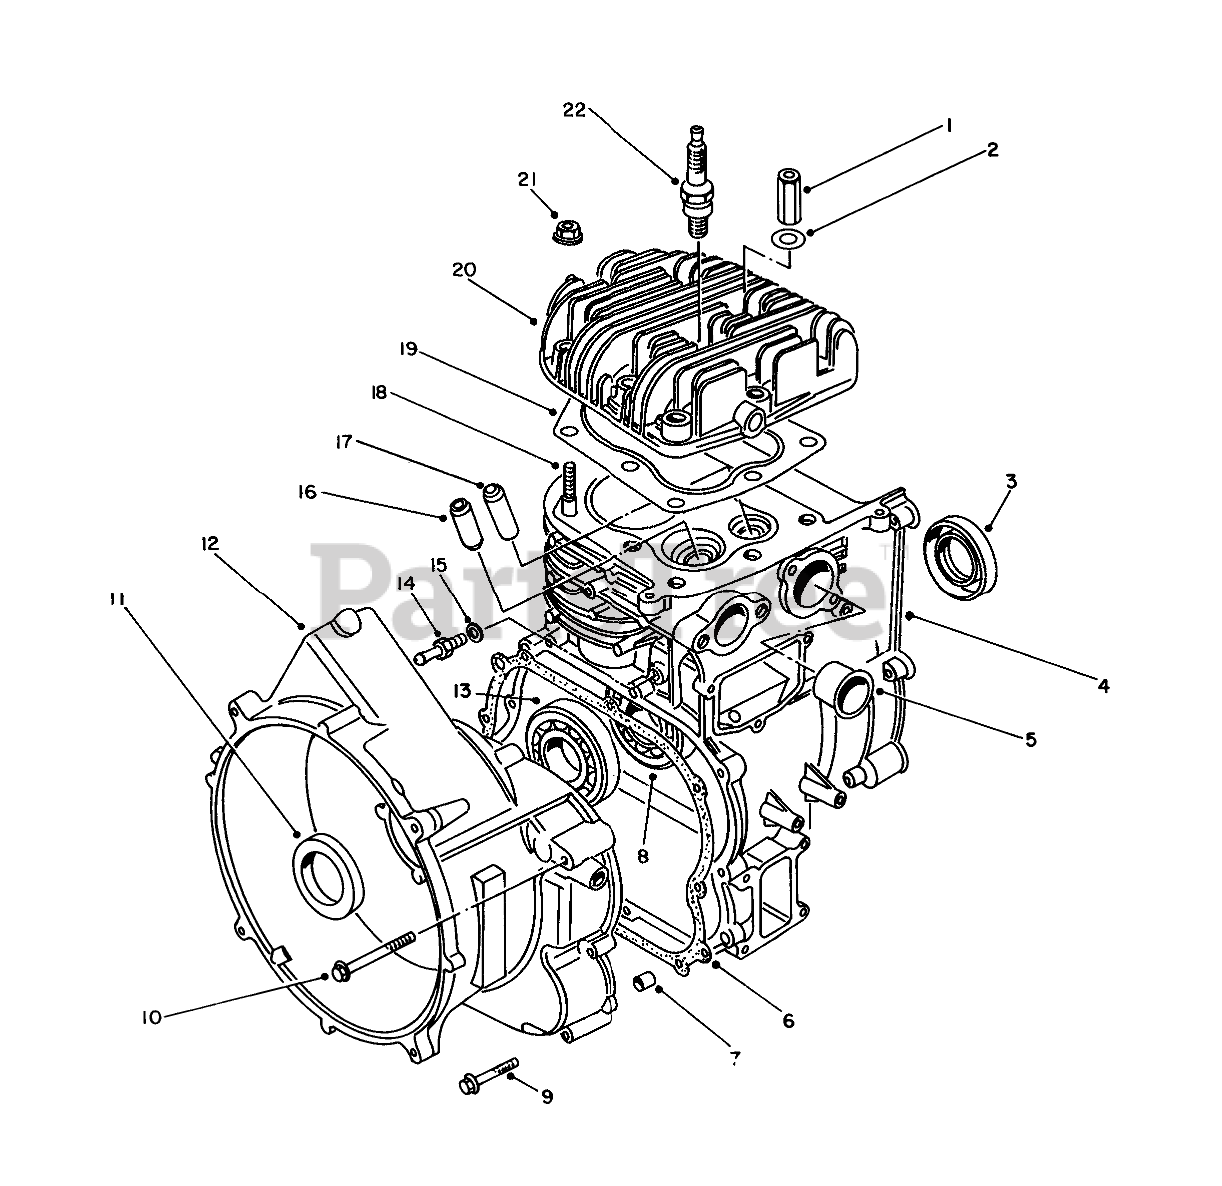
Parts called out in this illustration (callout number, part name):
2	Washer
3	OIL SEAL
4	Cylinder Assembly
5	Exhaust Guide
6	Gasket
8	Screw
11	OIL SEAL
12	Cover Assembly
13	Screw
14	Union
15	Gasket
16	Bolt
17	VALVE GUIDE
18	Stud Bolt
19	CYL HEAD GASKET
20	Head-Cylinder (53.8CC)
22	SPARK PLUG
